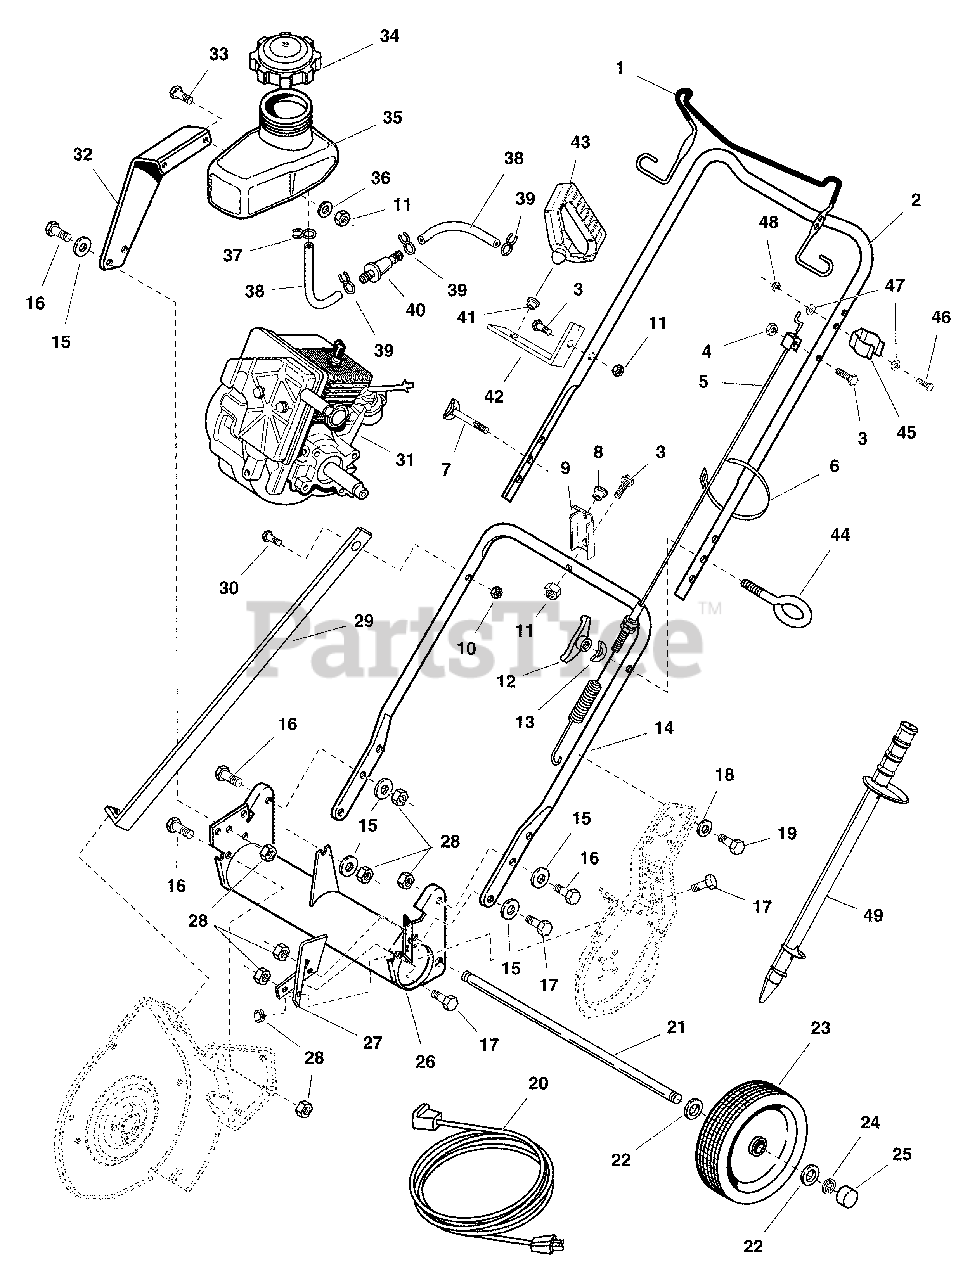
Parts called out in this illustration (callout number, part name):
1	HANDLE, Auger Control
2	HANDLE, Upper
3	CAPSCREW, Hex Hd., 1/4-20 x 1-1/4
4	NUT,Hex Centerlock, 1/4-20
5	CABLE, Auger Control
6	TIE, Self Locking
7	BOLT, Rd. Hd., 5/16-18 x 1-3/4
8	SNAP BUSHING, 3/8
9	BRACKET, Chute Rotator Rod
10	NUT, Hex Lk., #10-24
11	NUT, Hex Lk. Esna, 1/4-20
12	KNOB, Wing
13	WASHER, Curved, 5/16
14	HANDLE, Lower
15	WASHER, 3/4
16	CAPSCREW, Hex Hd., 5/16-18 x 3/4
17	CAPSCREW, Hex Hd., 5/16-18 x 1
18	LOCKWASHER, 5/16
19	CAPSCREW, Hex Hd., 5/16-18 x 3/4
20	CORD,Extension (Electric Start Models)
21	SHAFT, Axle
22	WASHER
23	TIRE, Semi-pneumatic
24	RING, Retainer, Ext., #37
25	CAP,Hub
26	FRAME ASSY.
27	BRACKET, Reinforcement
28	NUT, Hex Lk.,Esna, 5/16-18
29	STRAP, Support
30	SCREW, Hex Wshr. Hd., #10-24 x 1-1/4
32	BRACKET, Fuel
33	CAPSCREW, Hex Hd., 1/4-20 x 3/4
35	TANK, Fuel
36	WASHER
37	CLAMP, Hose
38	HOSE, Fuel, 5-1/2 long
39	CLAMP, Wire Form
40	FILTER, Gas
41	SNAP BUSHING, 1/4
42	BRACKET, Starter Handle
43	HANDLE, Start (Mitten)
44	HOLDER, Clean-Out Tool, Lower
45	HOLDER, Clean-Out Tool, Upper
46	SCREW, #10-24 x 1-1/4, Hex Head Cap
47	WASHER, #10 Internal Tooth Lock
48	NUT, #10-24 Hex Center Lock
49	TOOL, Clean-Out
